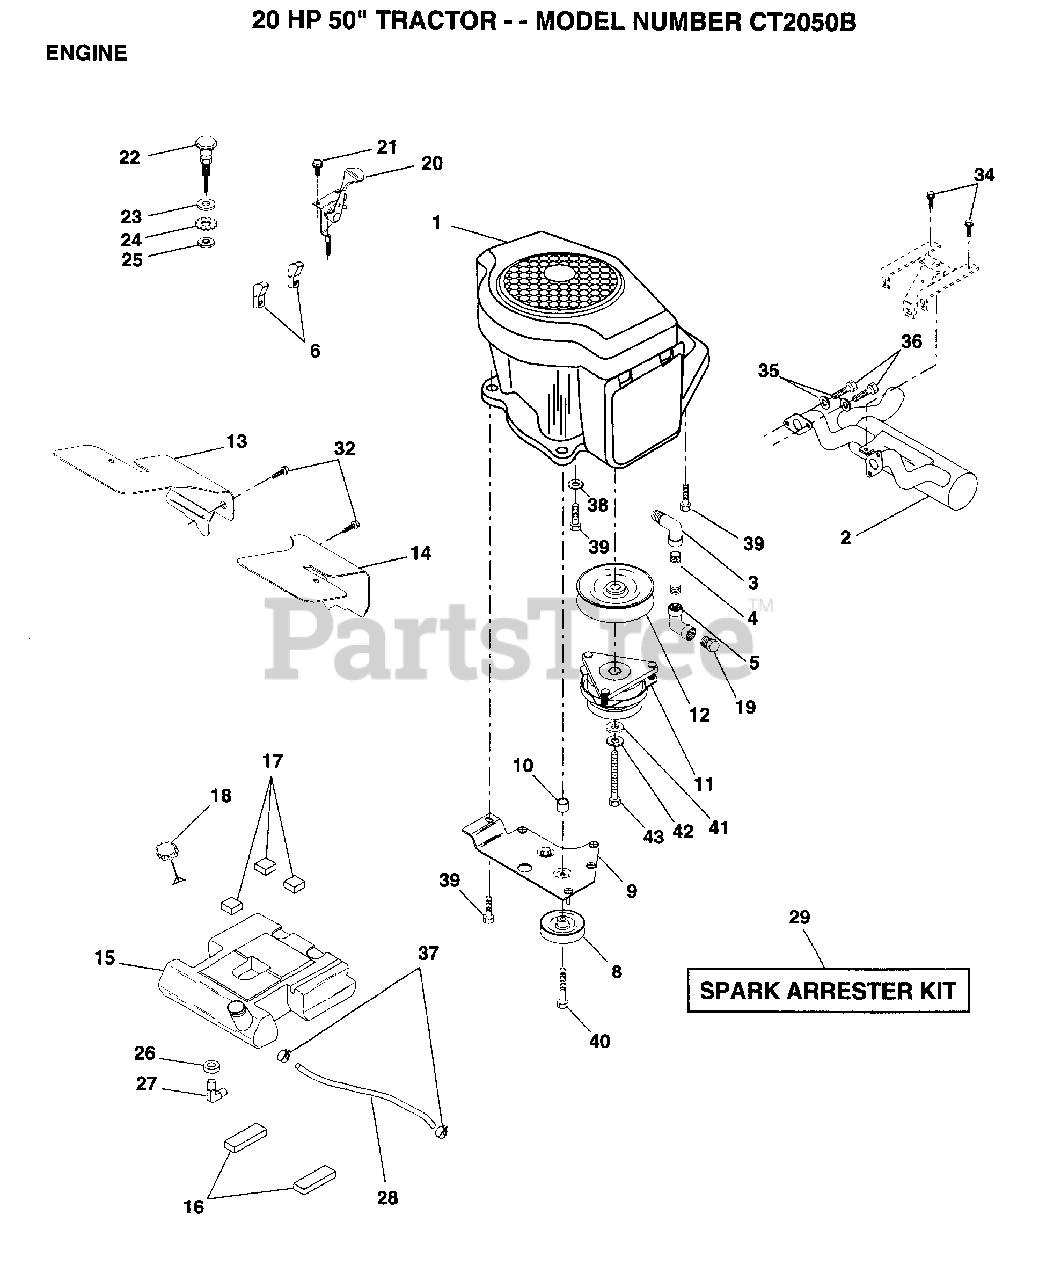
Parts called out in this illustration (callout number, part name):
1	ENGINE KOHLER MODEL
3	STREET ELBOW LT
4	PIPE NIPPLE
5	ELBOW
6	CLAMP.TUBE.DBL.EN
10	BUSHING.
12	PULLEY.ENGINE.VGT
13	BAFFLE.AIR.LH.K
16	PAD IDLER TI
17	PAD-SPACER LT
18	CAP ASM FUEL
19	PLUG T
20	CONTROL THTL 37
21	SCREW LT
22	"CONTROL.CHOKE.51"""
23	WASHER
24	LOCKWASHER
26	BUSHING OUTLET T
27	STEM.TANK.FUEL
29	SPARK ARREST KIT
32	SCREW LT
34	SCREW
35	LOCKWASHER
36	SCREW
37	HOSE CLAMP
38	LOCKWASHER
39	SCREW LT
40	SCREW.3/8-16X3.25
41	WASHER
42	LOCKWASHER
